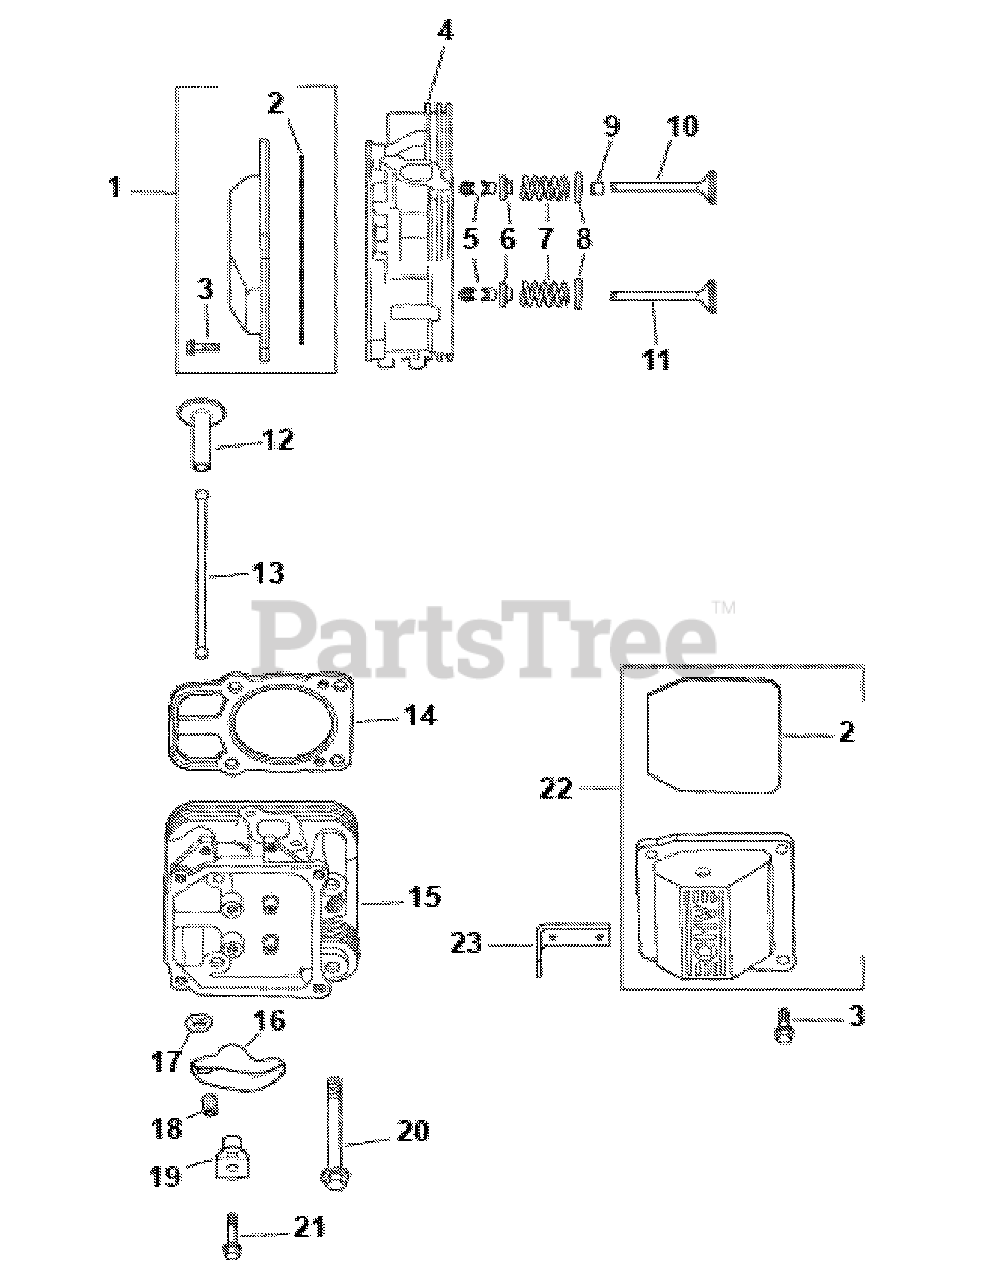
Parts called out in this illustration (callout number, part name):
1	Valve Cover Kit
2	O-Ring
3	Hex Flange Screw
4	Head Assembly # 1 Cylinder
5	Retainer Kit
6	Valve Spring Cap
7	Valve Spring
8	Spring Retainer
9	Valve Stem Seal
10	Intake Valve (Std.)
11	Exhaust Valve (Std.)
12	Tappet
14	Cylinder Head Gasket Kit
15	Head Assembly # 2 Cylinder
16	Rocker Arm
19	Rocker Arm Pivot
20	Hex Flange Screw
21	Hex Flange Screw
22	Valve Cover Breather Kit
23	Lifting Strap
